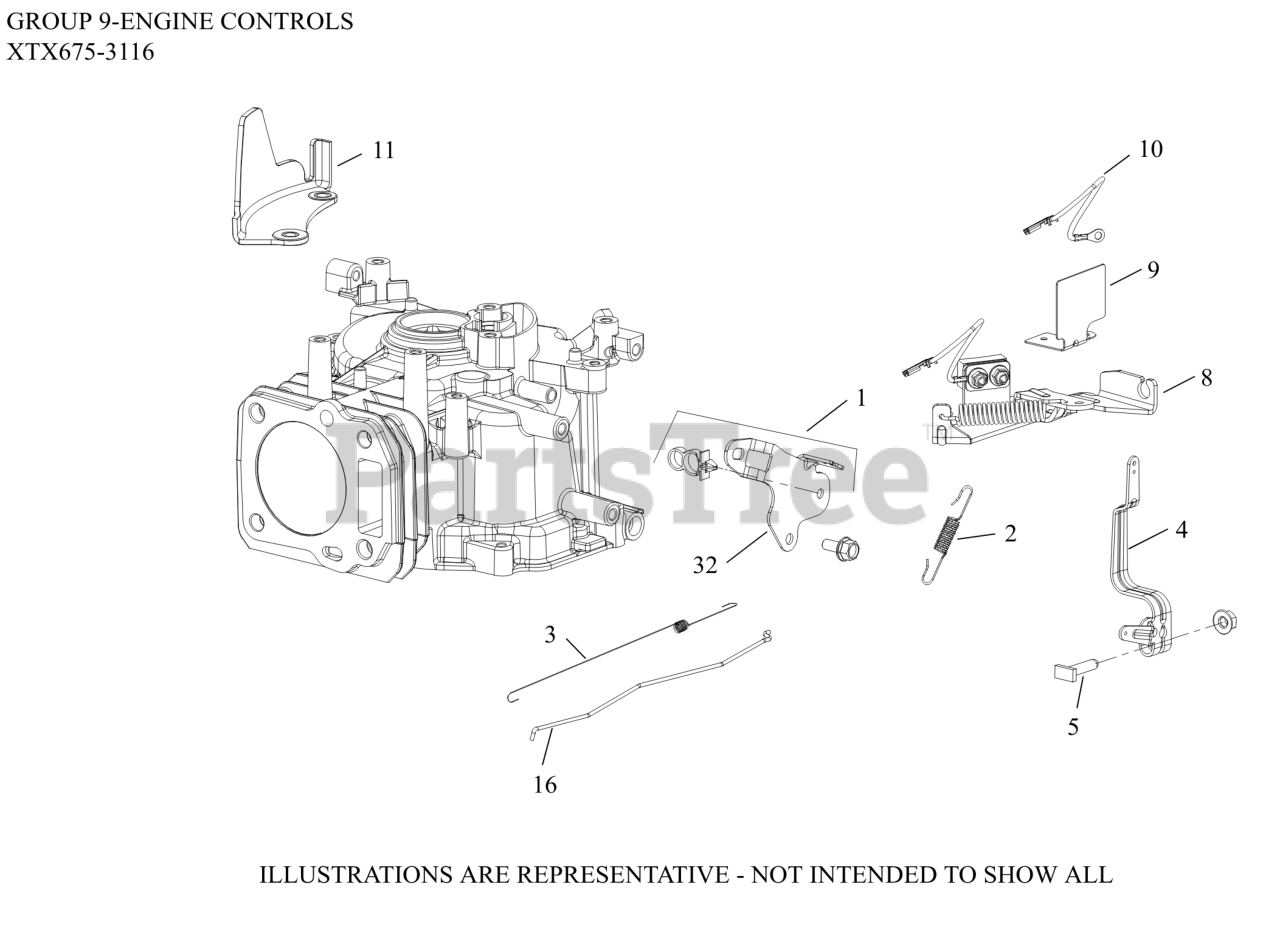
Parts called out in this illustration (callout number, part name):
1	BRACKET ASSEMBLY, FIXED SPEED CONTROL
2	SPRING, GOV (2800-3300 RPM)
3	SPRING, LINKAGE
5	SCREW, RECTANGLE HEAD (M6)
8	BRAKE ASSEMBLY
9	GUARD, BRAKE - USE 14 314 30-S
10	LEAD, KILL (BRAKE TO IGN. MODULE)
11	GUARD, FINGER
16	LINKAGE, GOVERNOR-(#1407927S)
32	BRACKET, FIXED SPPED - DISCONTINUED
34	LEVER, GOVERNOR
